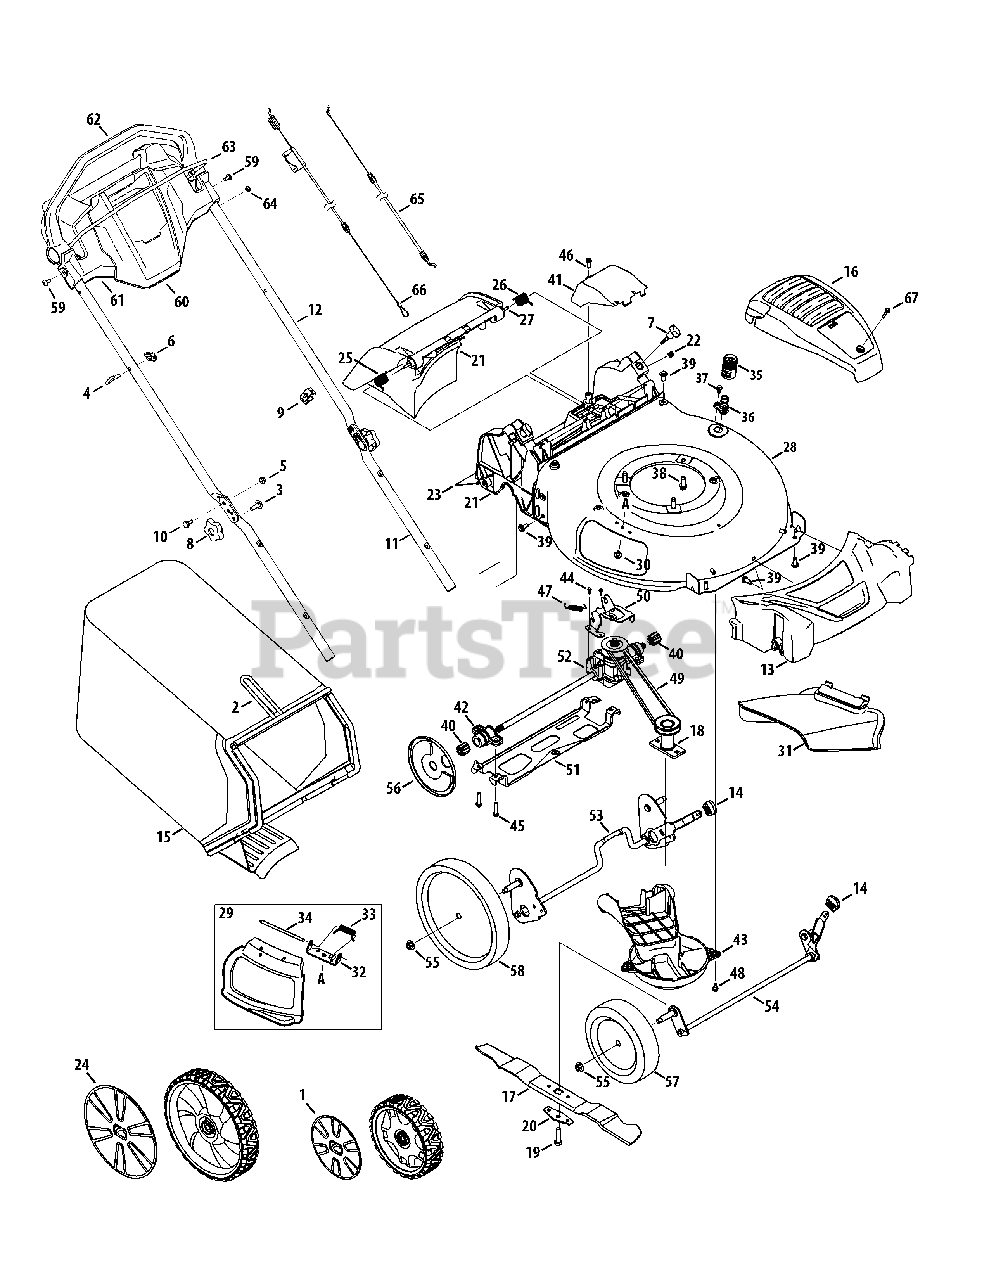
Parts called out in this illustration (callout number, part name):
1	Hubcap, 8"
2	Grass Catcher Frame
3	Carriage Screw ,5/16-18
4	Rope Guide
5	Nut, Flange Lock, 1/4-20
9	Conduit Clip
10	Shdr. Screw, .375 x .126 x 1/4-20
11	Lower Handle
12	Upper Handle
13	Front Cover
14	Adjustment Knob
16	Engine Shroud
17	Mulching Blade
18	Blade Adapter
19	Screw, 3/8-24 x 1.50
20	Blade Bell Support
21	Rear Discharge Door Assembly
22	Nut, Sq., 1/4-20
23	Trail Shield
24	Hubcap, 11"
25	Torsion Spring - RH
26	Torsion Spring - LH
29	Mulch Plug (Incl. 32-34)
31	Side Discharge Chute
32	Chute Deflector Bracket
33	Torsion Spring
35	Water Nozzle Adapter
36	Water Nozzle
37	Shoulder Screw, 1/4-20 x 0.50
38	Screw, tt, 3/8-16 x 1.00
39	Screw, 5/16-14 x .750
40	Spur Gear, 9T
41	Transmission Cover
42	Bearing Assembly
43	Engine Baffle
44	Screw, Hex Washer, .159 x .43
45	Screw, 1/4-15 x 1.25
46	Screw, 1/4-15 x .750
47	Exten. Spring, 2.405
48	Shoulder Screw, 1/4-20 x 0.50
50	Transmission Bracket
51	Rear Support Bracket
52	Transmission Assembly
53	Rear Axle Assembly
54	Front Axle Assembly
55	Flange Lock Nut, 3/8-16
56	Wheel Dust Cover
57	Front Wheel, 8 x2
58	Rear Wheel, 11 x 2
59	Screw, 1/4-14 x .625
60	Trim Console
61	handle Console
62	Drive Handle
64	Shoulder Spacer, .18 x .315 x .09
65	Control Cable
66	Drive Cable
67	Screw, #10-16 x 1.25
